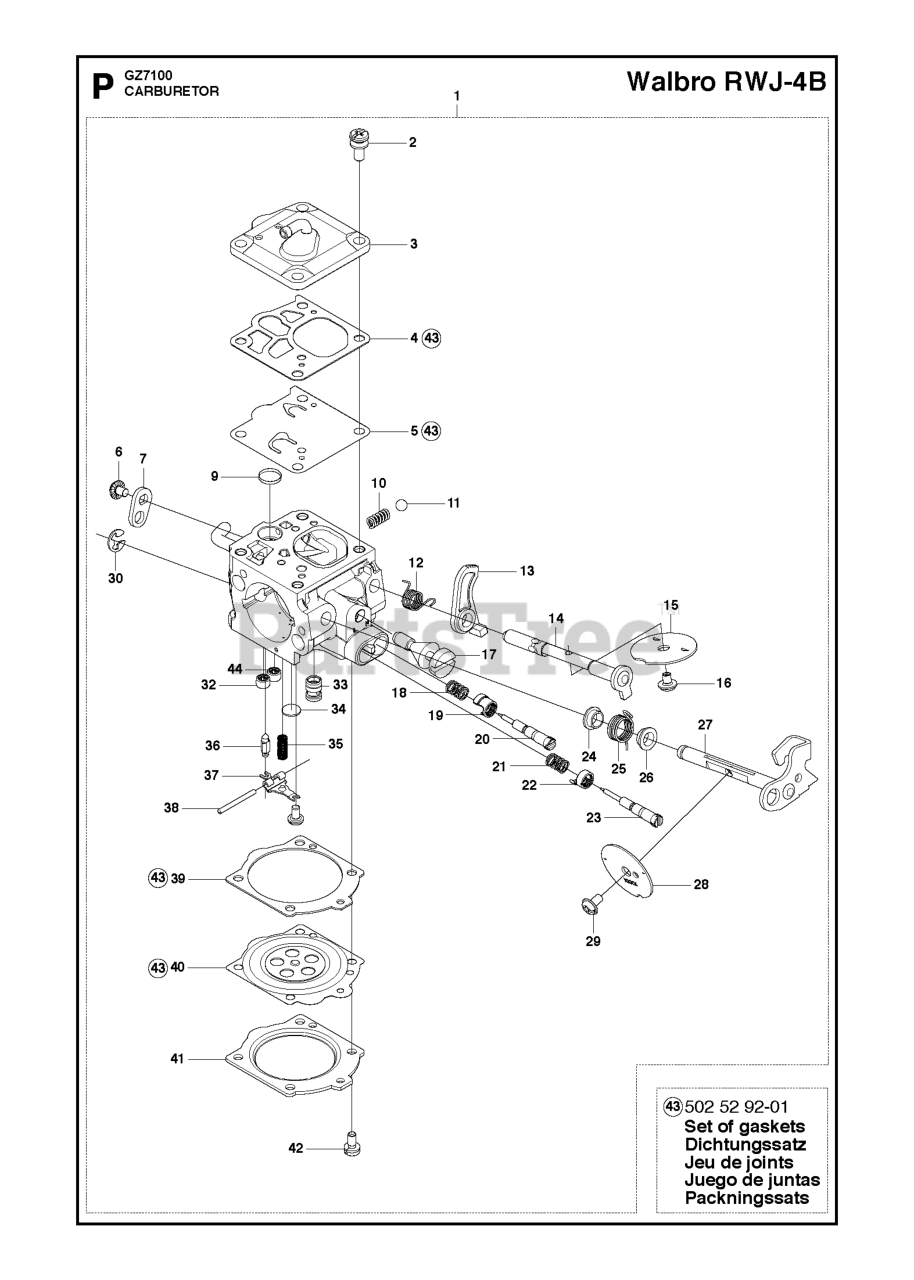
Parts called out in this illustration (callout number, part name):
1	CARBURETTOR RWJ-4B
2	SCREW W/ WASHER
3	PUMP COVER
4	GASKET
5	DIAPHRAM PUMP
6	SCREW
7	LEVER CHOKE
9	FUEL INLET SCREEN
10	SPRING
11	BALL 394
12	SPRING CHOKE
13	LEVER
14	SHAFT ASSY
15	VALVE
16	SCREW
17	IDLE SPEED SCREW
18	SPRING
19	LIMITER CAP
20	NEEDLE
21	SPRING
22	LIMITER CAP
23	NEEDLE
24	BUSHING
25	SPRING
26	BUSHING
27	SHAFT ASSY
28	VALVE THROTTLE
29	SCREW
30	E CLIP
32	CHECK VALVE IDLE JET
33	MAIN NOZZLE
34	PLUG WELCH
35	SPRING
36	INLET NEEDLE
37	LEVER
38	PIN
39	GASKET
40	DIAPHRAGM ASSY
41	DIAPHRAM COVER
42	RP SCREW W/ WASHER
43	GASKET KIT
44	CHECK VALVE ASSY
